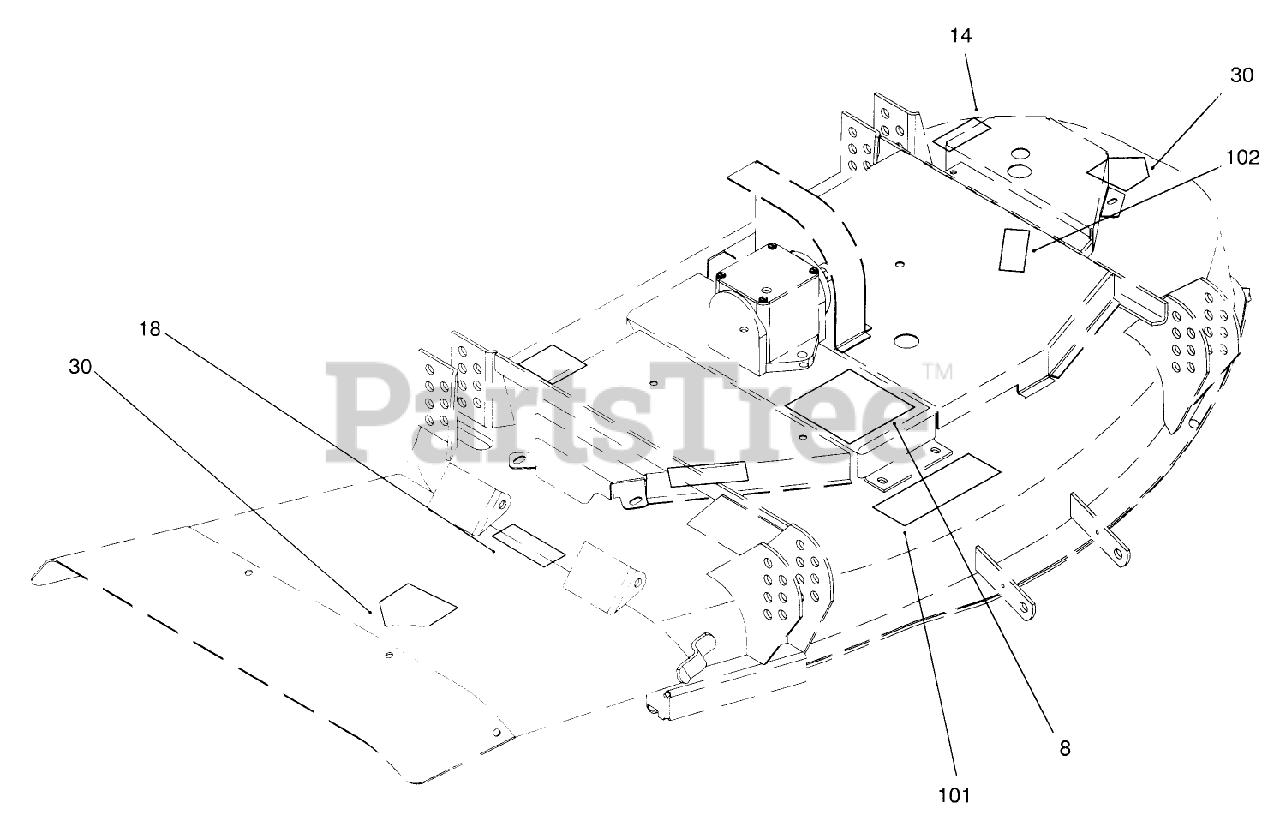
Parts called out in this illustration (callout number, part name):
8	DECAL-44 INCH
14	Decal-Blade Bolt
18	DECAL-WARNING, DEFLECTOR
30	DECAL-DANGER
101	DECAL-DANGER
